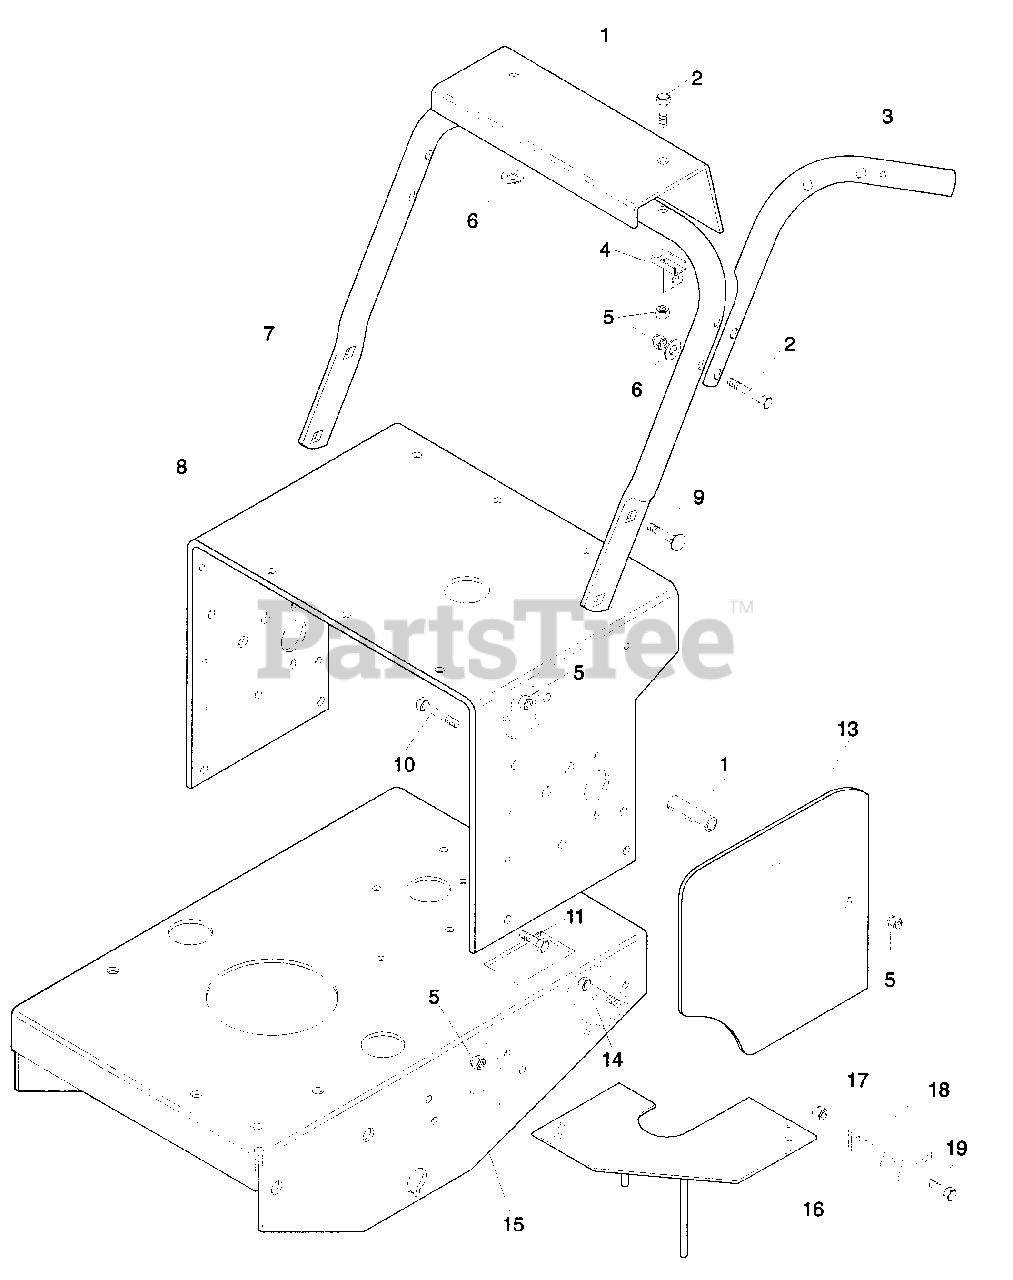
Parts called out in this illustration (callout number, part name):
1	Panel, Instrument
2	Bolt-Hex .38-16 x 2.00 Grade 5
3	Handlebar Left Hand
3	Handlebar Right Hand
4	PTO Lever Mounting Bracket
5	Nut-Locking-Center .375-16
6	Washer-Flat-Steel .406 x .812 x .065
7	Lower Handlebar, Pro 100
8	Bolt-Round Head Square Neck .38-16 x 1.0
9	Bolt-Hex .38-16 x 4.00
10	Bolt-Hex .38-16 x 1.00 Grade 5
11	Bolt-Hex .38-16 x 4.00 Grade 5
12	Bushing, Spacer, 3.25 x 3/8 ID x 5/8 OD
13	Guard, Drive Pro-100 Side Cover
14	Bolt-Hex.38-16 x 1.50 Grade 5
15	Pro-150 Main Frame
16	Belt Brake Finger-Deck Clutch
17	Nut-Locking Center .312-18
18	Cleaner, Pulley Groove Left Hand
18	Cleaner, Pulley Groove Right Hand
19	Bolt-Hex .31-18 x.75 Grade 5
